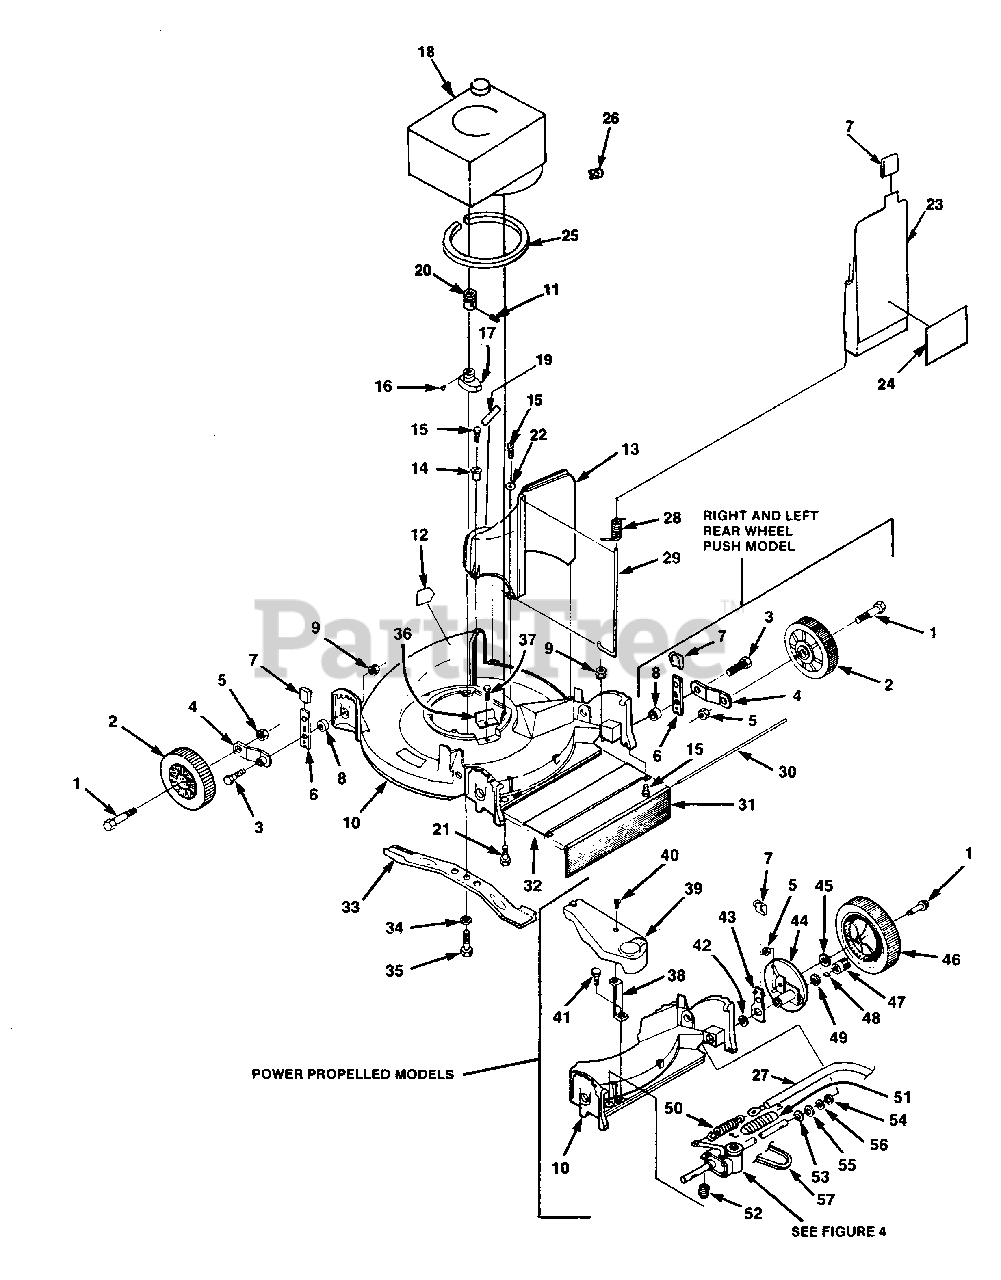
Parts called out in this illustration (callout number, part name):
1	BOLT- Axle 3/8-24
2	WHEEL & TIRE
3	BOLT- Hex hd. 5/16-18
4	ARM- Wheel hgt. adjusting
5	NUT- Hex 3/8-24
6	SPRING- Index
7	KNOB- Indexing spring
8	SPACER- Index spring
9	NUT- Flange 5/16-18
10	DECK- 21"
12	DECAL- Warning
13	CHUTE- Discharge
14	SIMPSON EYELET
15	SCREW- Hex hd. 1/4-20 x 3/4
16	KEY- Woodruff #61
17	ADAPTER- Blade
18	ENGINE- 2 Cycle I.C.
20	PULLEY- Drive
21	SCREW- 3/8-16 x 1 1/2
22	WASHER
23	DOOR- Chute
24	DECAL- Door
25	RING- Engine
26	STOP- Rope
27	CABLE- Traction
28	SPRING- Door
29	PIN- Hinge
30	ROD- Drag flap
31	FLAP- Drag
32	COVER- Rear
33	BLADE- 21"
34	WASHER- Lock
36	COVER- Belt opening
37	SCREW- Hex hd. 1/4-20 x 1/2
39	COVER- Drive
40	SCREW- Rd. hd. 1/4-20 x 3/4
41	SCREW- Hex hd. 10-16 x 1/2
42	SPACER- Hgt. Adj.
43	SPRING- Index
44	DRIVE WHEEL SUPPORT
45	WASHER- Flat
46	WHEEL & TIRE
47	PINION (R.H.)
48	PAWL- Pinion
49	WASHER- Flat
50	SPRING- Traction lever
51	COVER- Spring
52	SPRING- Compression
53	RING- Eaton
54	WASHER- Flat
56	WASHER- Shim
57	BELT- Drive
